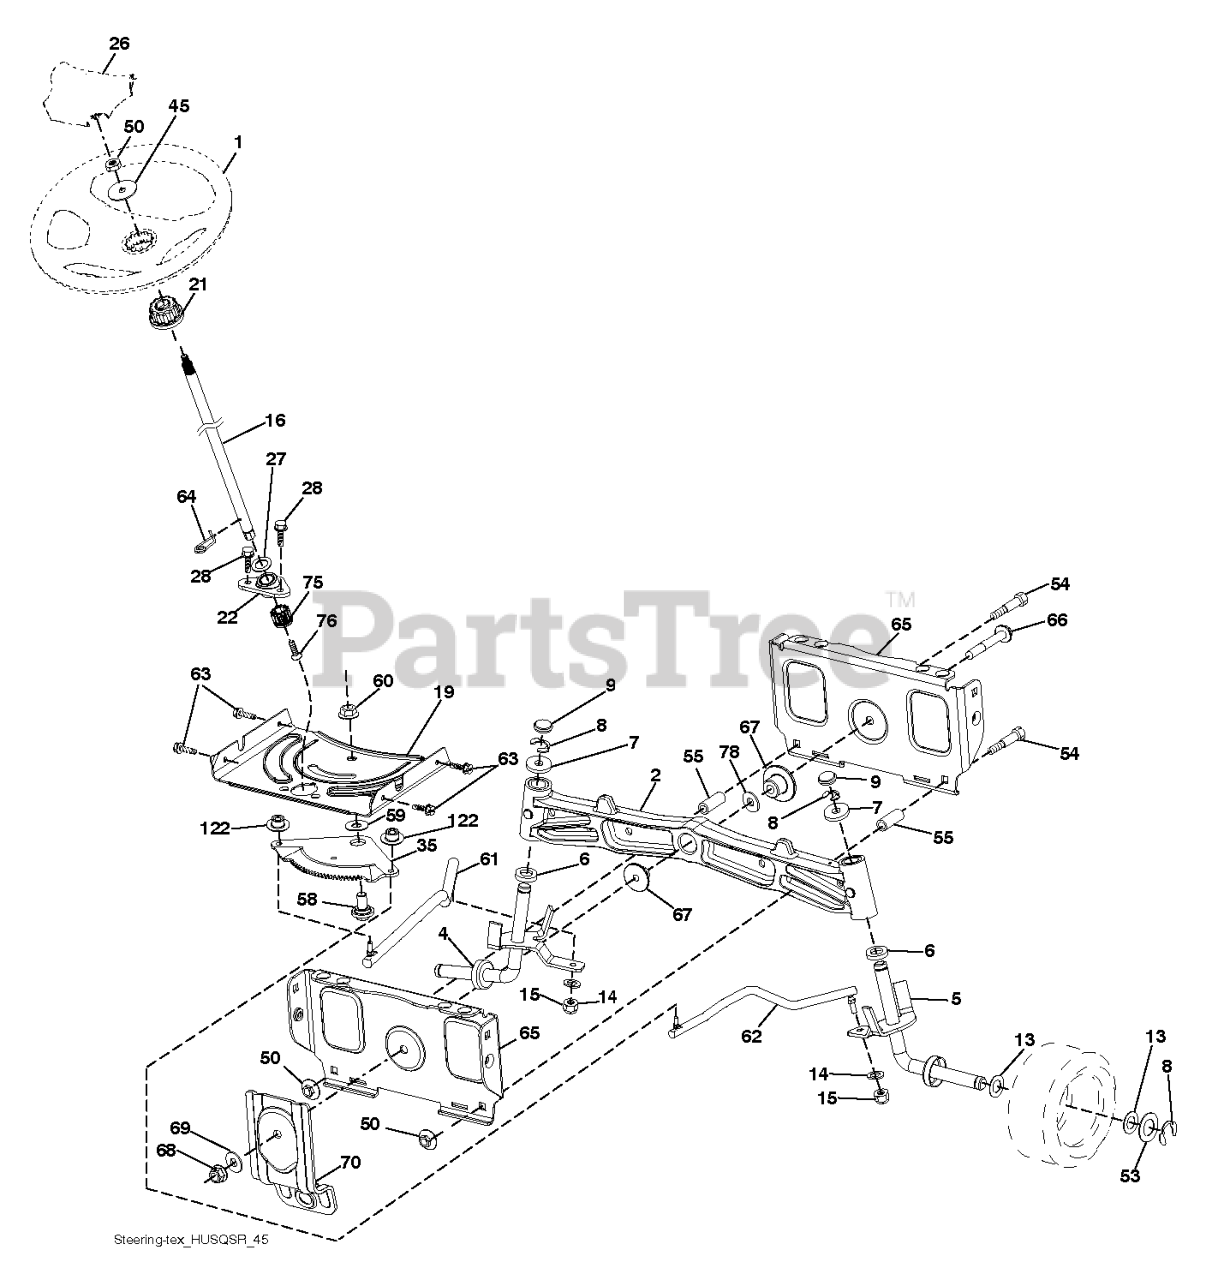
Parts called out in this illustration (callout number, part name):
1	WHEEL.STEER.HUSQ.SR.498.OVMLD
2	AXLE.CAST.IRON
4	SPINDLE.ASM.LH
5	SPINDLE.ASM.RH
6	THRUST WASHER
9	CAP.SPINDLE.BLACK
14	WASHER, LOCK 3/8
15	NUT CROWNLOCK 3/8-24
16	SHAFT.STEER.2HIGH.SPLND.PLATED
19	PLATE.STEER.DDL.NLT/NG
21	ADAPTER.WHEEL.STEER.SPLND.ALUM
22	BEARING.SHAFT.STEER.LOWER.625
26	INSERT.CAP.WHL.STRG.HUSQ.PREM
27	WASHER LT
28	SCREW, 3/8-16X3/4
35	GEAR.SECTOR.PLATE.DDL.
45	WASHER.3/8ID.2-3/8OD.12GA.PLTD
50	NUT LOCK FLG 3/8-16 UNC
53	WASHER.HARDENED
55	SPACER.BRACE.AXLE
58	BOLT.SHOULDER.SECTOR.P
59	WASHER.THURST.SECTOR.S
60	NUT FLANGE LOCK 5/8-11
61	DRAGLINK.LH.BALLSTUD.D
62	DRAGLINK.RH.BALLSTUD.D
63	SCREW
64	RETAINER.CLIP.SPRING.S
65	BRACE.AXLE.FRONT.NLT/N
66	BOLT HEX FGHD 7/16-14 X 3 SERR
67	BUSHING.PM.FRONT AXLE
68	NUT.LOCK.FLANGE.7/16
69	WASHER.1.5X.505X.118
70	BRACKET.FRT.DECK.SUSP.RR.MT431
75	PINION.ZINC PLATED
76	SCREW HEAD SOCKET LRVB
78	THRUST WASHER
122	CAP.GEAR.SECTOR.TEX
